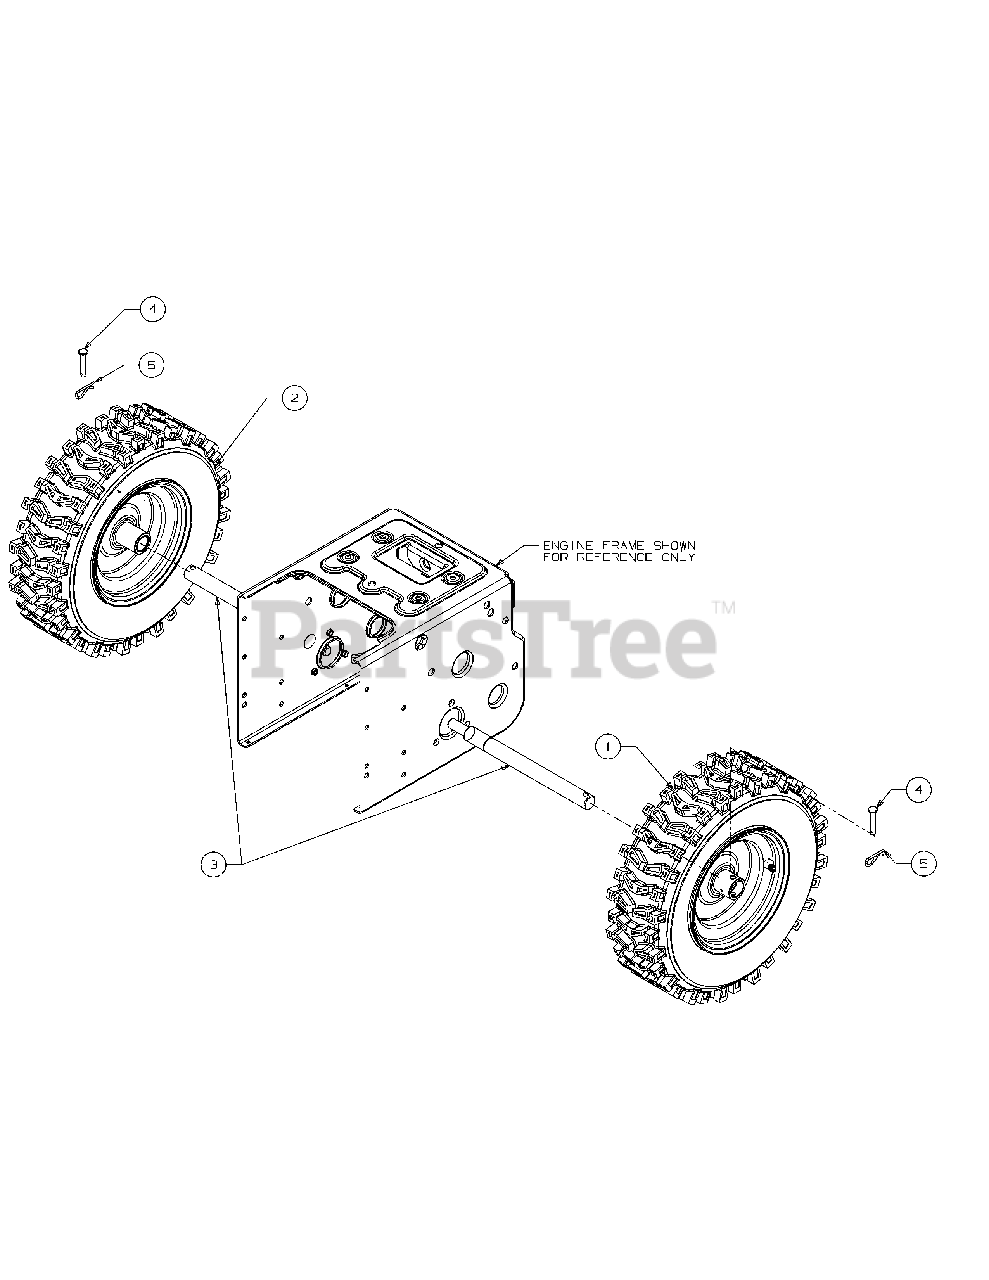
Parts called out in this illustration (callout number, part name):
1	Wheel Asm-LH X-Trac
2	Wheel Asm-RH X-Trac
3	Axle Wheel
4	Pin:Clevis
5	Pin-Cotter
